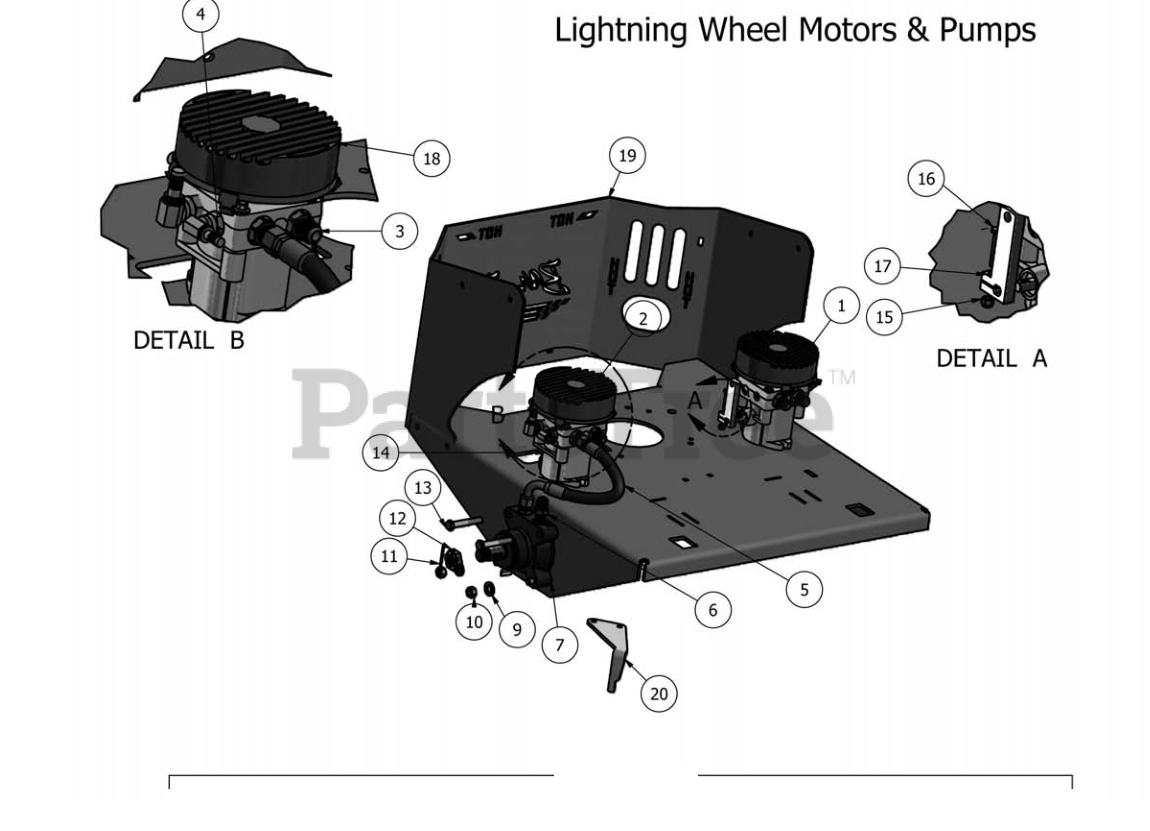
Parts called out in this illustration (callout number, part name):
1	Left Hydraulic Pump 12cc
3	Hydraulic Fitting
4	3/8" x 9/16" Male Fitting
5	16" Hydraulic Hose
6	Hydrauilc Fitting (Wheel Motor)
7	15cc Parker Wheel Motor Right
8	15cc Parker Wheel Motor Left
9	1/2" Lock Washer
10	1/2" Hex Nut
11	1/8" x 2 1/4" Cotter Pin
12	Castle Nut
13	1/2" 3" hex Bolt
14	Right Hydraulic Pump 12cc
15	1/4" Nylock Nut
16	1/4" x 1 1/2" Bolt
19	Pup Rear Plate
20	PTO Engager Holder
